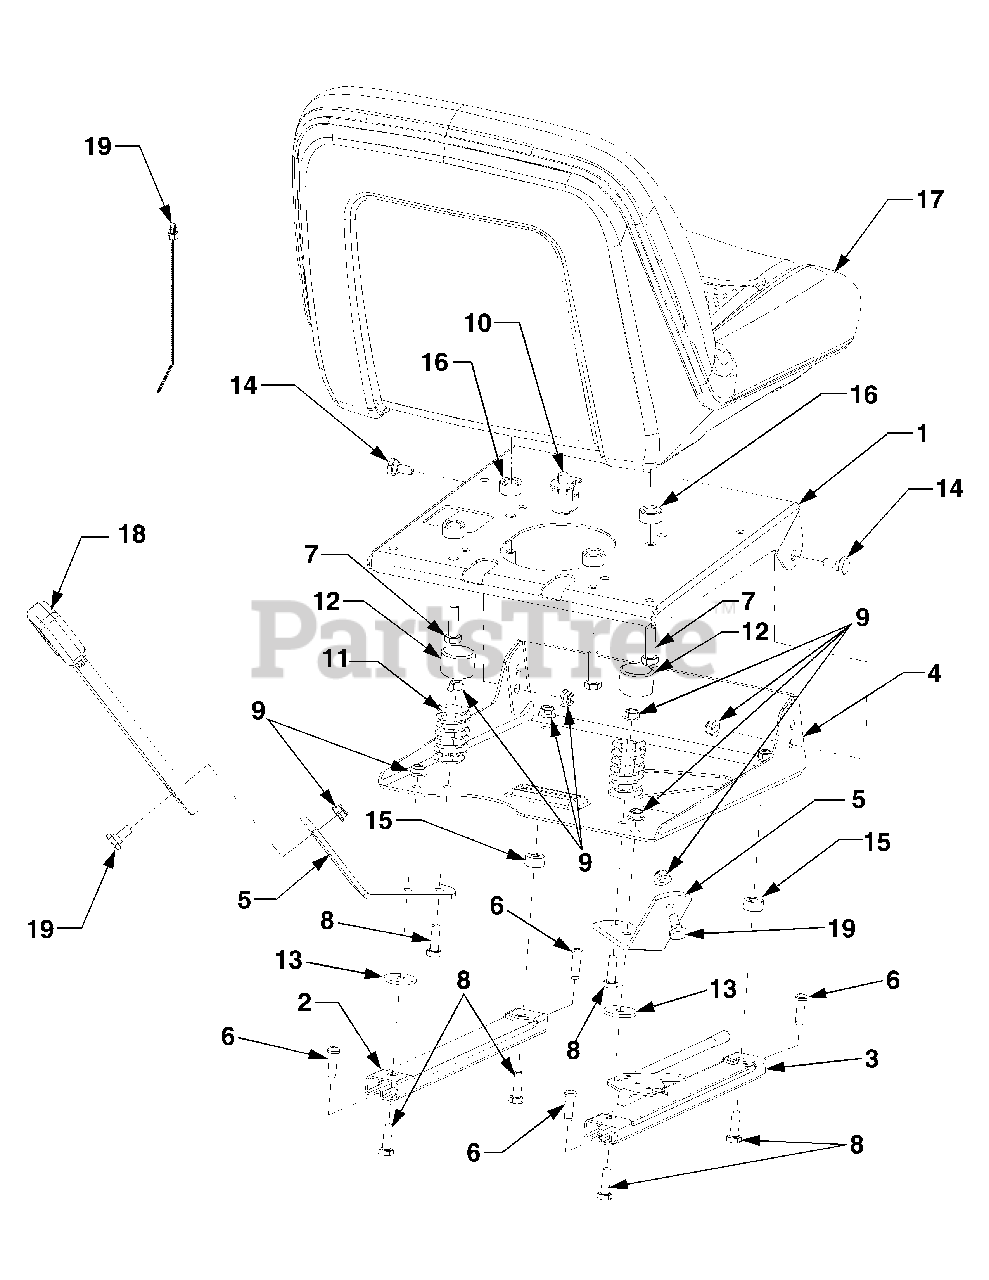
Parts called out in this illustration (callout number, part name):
1	Bracket, Seat Pivot
2	Track, Seat - w/o Latch
3	Track, Seat - w/Latch
4	Bracket, Seat Support
5	Bracket, Seat Belt
6	Screw, Pan Hd. Mach. 5/16-18 x 1.0
7	Screw, Hex Cap, 3/8-16 x 1.25 GR5
8	Screw, Hex Cap, 5/16-18 x 1.0 GR5
9	Nut, Hx Insert Flnge Lk,
10	Switch, Seat, N/O
11	Spring, Compression
12	Cap, Spring
13	Washer, Flat, .33 x 1.25 x .12 .
14	Screw, Shoulder, .435 x .178:5/16-18
15	Spacer, .315 x .75 x .375
16	Spacer, .505 x .88 x .44
17	Seat, High Back
18	Belt Assembly, Seat
19	Tie, Push Mnt. Cable
